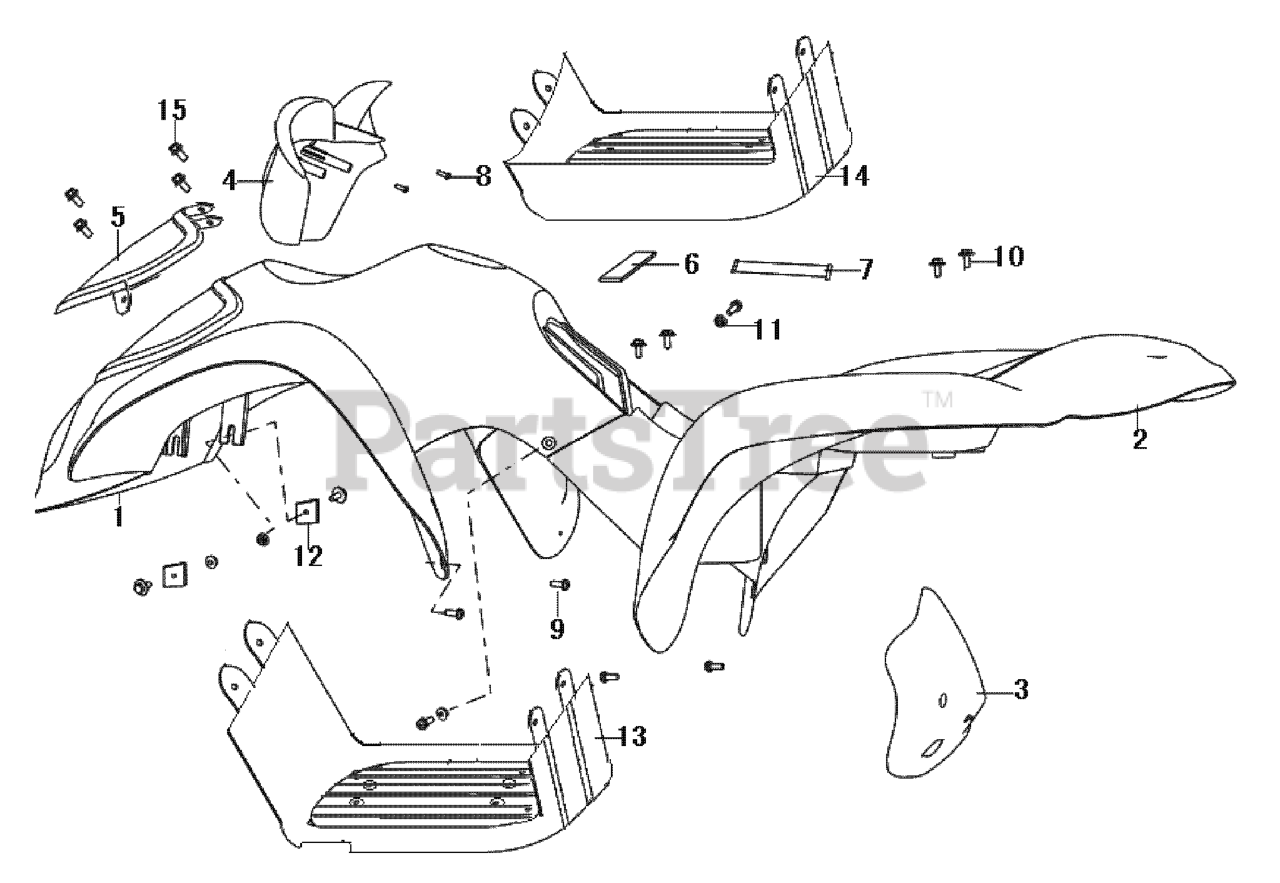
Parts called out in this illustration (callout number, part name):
1	COWLING, FRONT (BLUE)
2	COWLING, REAR (BLUE)
3	COVER, REAR (BLUE)
4	COWLING, HANDLEBAR (BLUE)
5	COVER, FRONT (BLUE)
6	BAND, BATTERY
7	BAND, TOOL KIT
10	SCREW W/WASHER
13	FOOTREST COVER, LEFT
14	FOOTREST COVER, RIGHT
